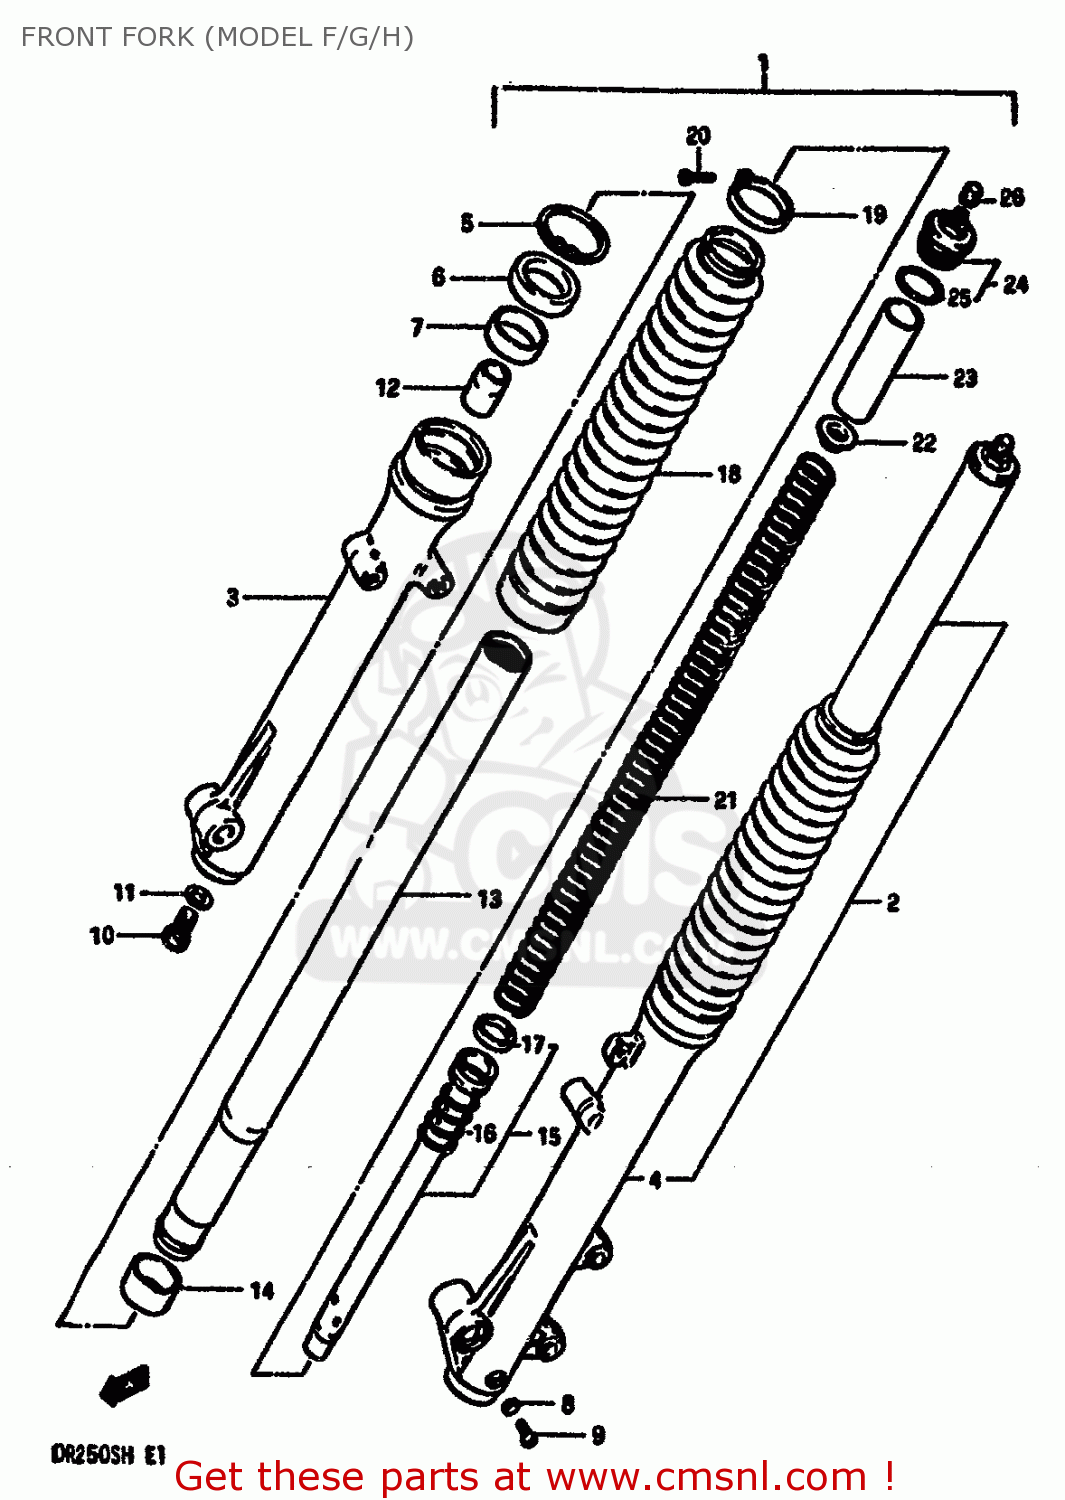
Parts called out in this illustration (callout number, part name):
1	DAMPER ASSY,RH (BLUE)
2	DAMPER ASSY,LH (BLUE)
3	TUBE,FORK,OUTER,RIGHT
4	OUTER TUBE,LH
5	6
6	SEAL,OIL
7	SLIDE METAL
8	GASKET,DRAIN,PLUG (NAS)
9	SCREW
10	BOLT,FORK CYLINDER(10X25)
11	GASKET (NAS)
12	PIECE,OIL LOCK
13	INNER TUBE
14	PISTON
15	CYLINDER,FRONT FORK
16	SPRING
17	RING,FRONT FORK PISTON
18	BOOT
19	BAND,BOOT
20	SCREW
21	SPRING
22	GUIDE,FRONT FORK SPRING C
23	COLLAR,SPRING
24	CAP,FR FORK INNER TUBE
25	O RING
26	CAP
